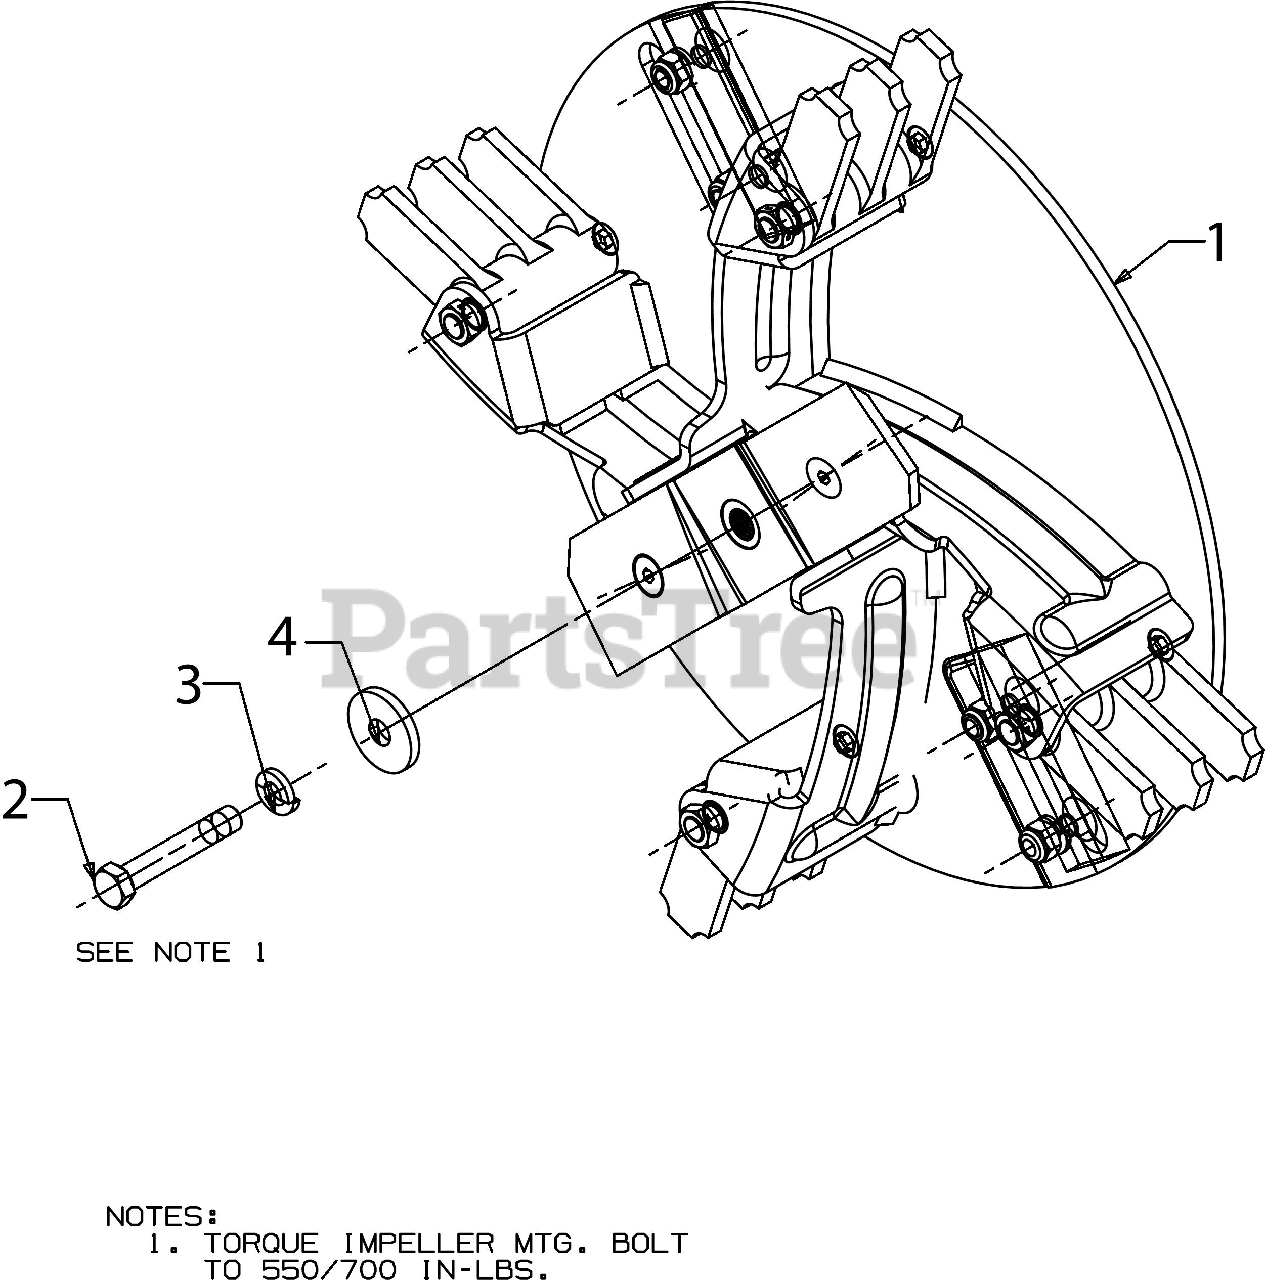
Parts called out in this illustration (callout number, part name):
1	IMPELLER ASSEMBLY
2	SCREW 3/8-24X2.25 GR8
3	LOCK WASHER 3/8HD
4	FLAT WASHER
